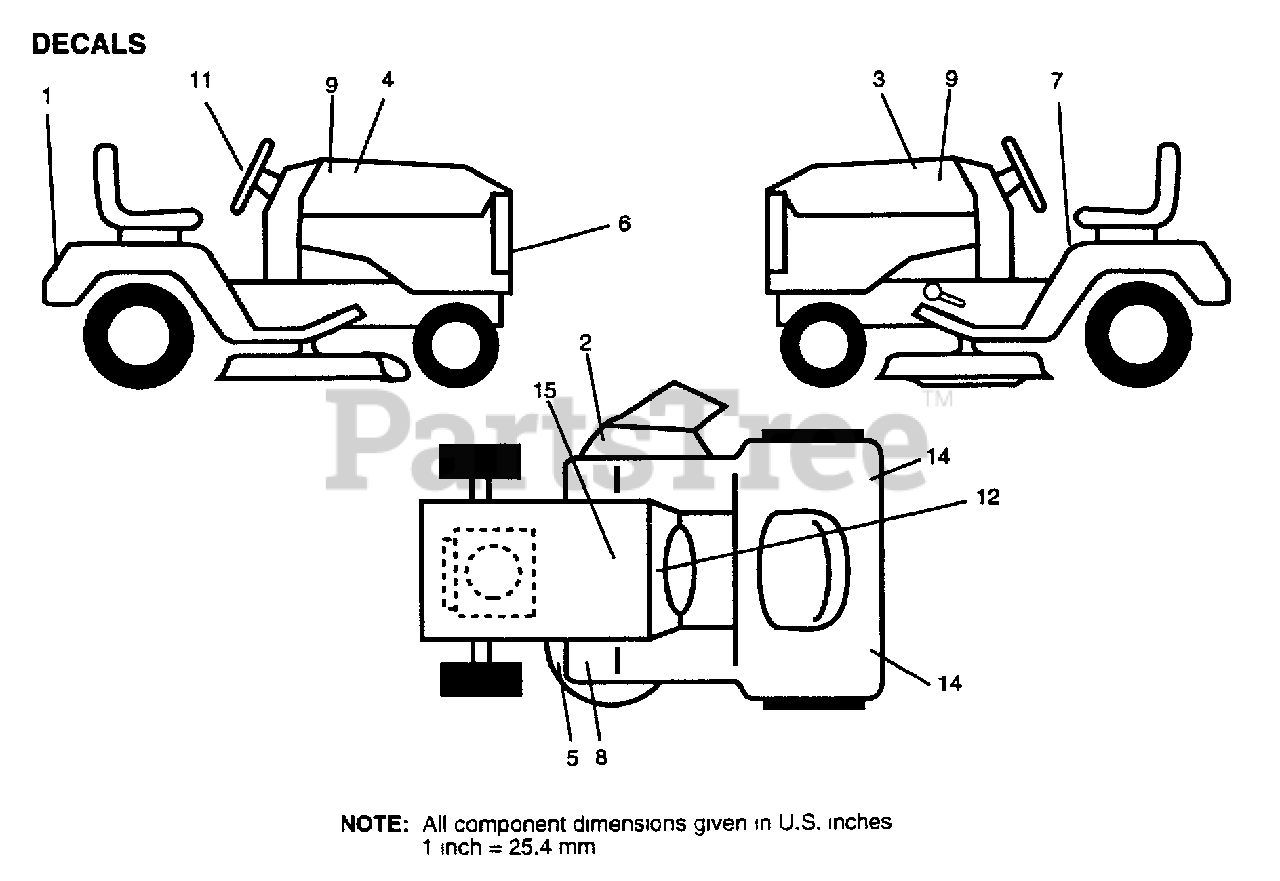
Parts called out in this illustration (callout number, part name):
1	DECAL.FENDER
2	"DECAL, WARNING"
3	DECAL.HOOD.LH.
4	DECAL.HOOD.RH.
5	"DECAL.V.BELT.44"""
6	DECAL.GRILLE
7	DECAL CAUTION
8	DECAL T
9	DECAL.HOOD.INSERT
11	DECAL INST STRWHL
12	DECAL.DASH.INSTR.
14	REFLECTOR-TAIL YT
15	DECAL
